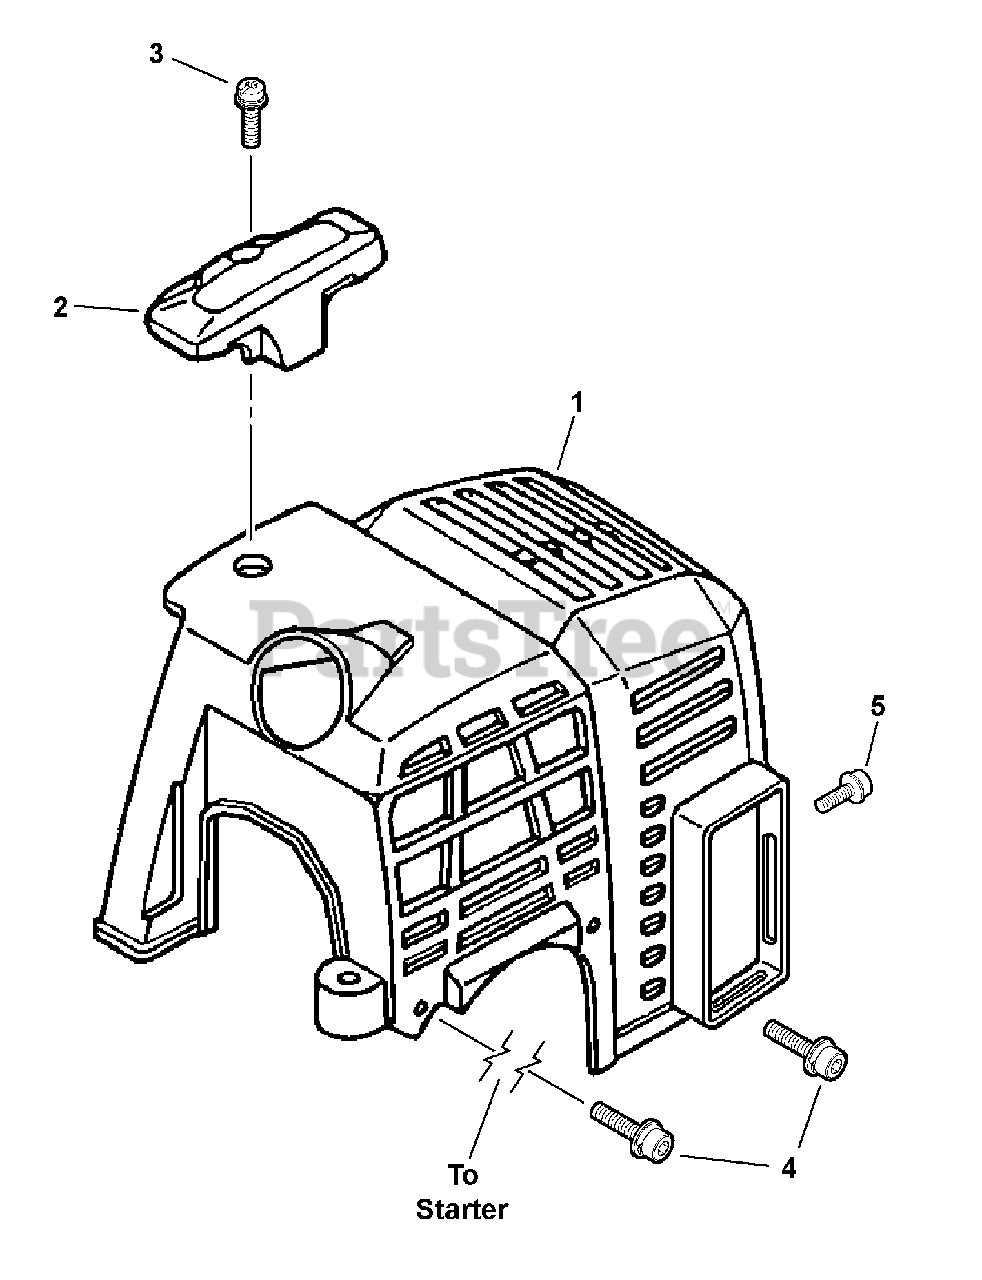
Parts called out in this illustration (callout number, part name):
1	Cover, engine
2	Guard, top
3	Screw 5x16
4	Screw 4x16
5	Screw 4x8
